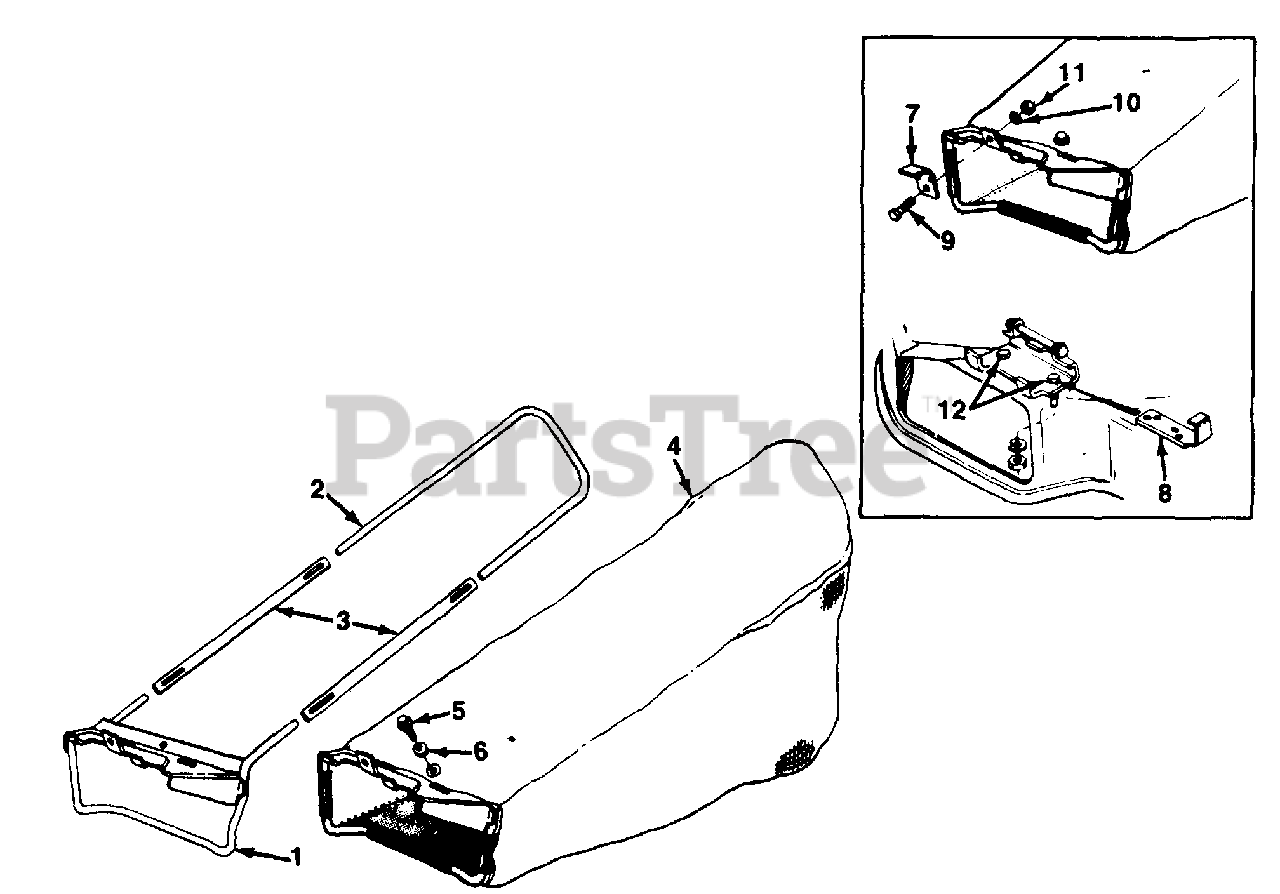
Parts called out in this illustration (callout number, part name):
1	Frame - Lower Ass'y.
2	Frame - Upper
3	Tube Support
4	Grass Bag
5	Hex Wash Hd. TT-Tap Scr. 1/4-20 x 5" Lg.
6	Bell-Wash. 1/4" I.D.
7	Deflector Stop
8	Support Plate
9	Hex Bolt 1/4-20 x .5" Lg.
10	L-Wash. 1/4" I.D.
11	Hex Nut 1/4-20 Thd.
12	Hex Bolt 1/4-20 x .62" Lg.
